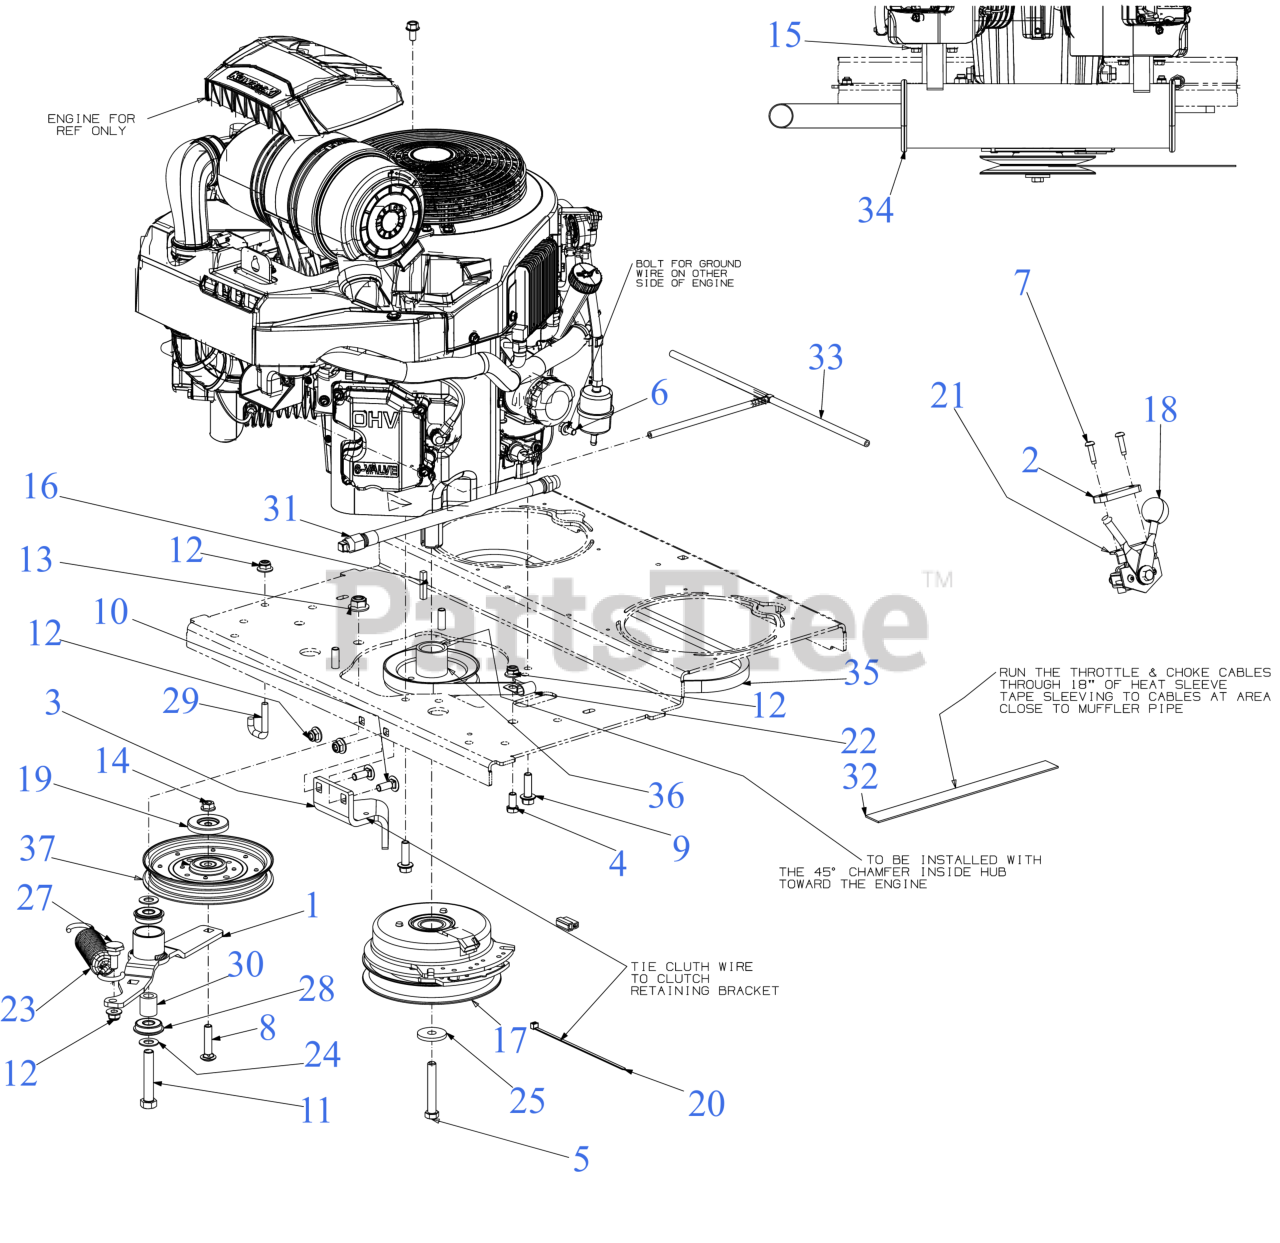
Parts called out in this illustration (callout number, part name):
1	TRANSMISSION IDLER BRACKET
3	CLUTCH RETAINER BRACKET
4	HEX SCREW 3/8-16 x .75
5	SCREW 7/16-20:2.75 GR5
6	SCREW M8 x 1.25 x 16MM GR8.8
7	SCREW 1/4-20 x 1.0
8	CARRIAGE BOLT 3/8-16 x 1.75 GR5
9	SCREW 3/8-16 x 1.25 GR5
10	CARRIAGE BOLT 3/8-16 x 1.00 GR5
11	SCREW 1/2-13 x 2.75 GR5
14	HEX LOCK NUT
15	HEX FLANGE NUT
16	SQUARE KEY 1/4 x 1.50
17	ELECTRIC PTO CLUTCH
19	PULLEY CAP
19	ROD SPRING HOOK
20	7" CABLE TIE
21	ELECTRONIC THROTTLE CONTROL
22	J TYPE CLIP
23	EXTENSION SPRING W/HOOK
24	FLAT WASHER .510 x .995
25	FLAT WASHER .45 x 1.5 x .172 HT
27	SHOULDER SCREW .625 x .302 x 3/8-16
28	ROLLER BEARING .5X1.37X.44
30	SPACER 0.51 x 0.88 x 1.00
31	OIL DRAIN HOSE
32	HEAT SHIELD 24"
33	ROLLOVER VENT HOSE ASSEMBLY
34	MUFFLER - KAWASAKI 1000
35	TRANSMISSION BELT
36	PULLEY - PUMP DRIVE
37	IDLER PULLEY
